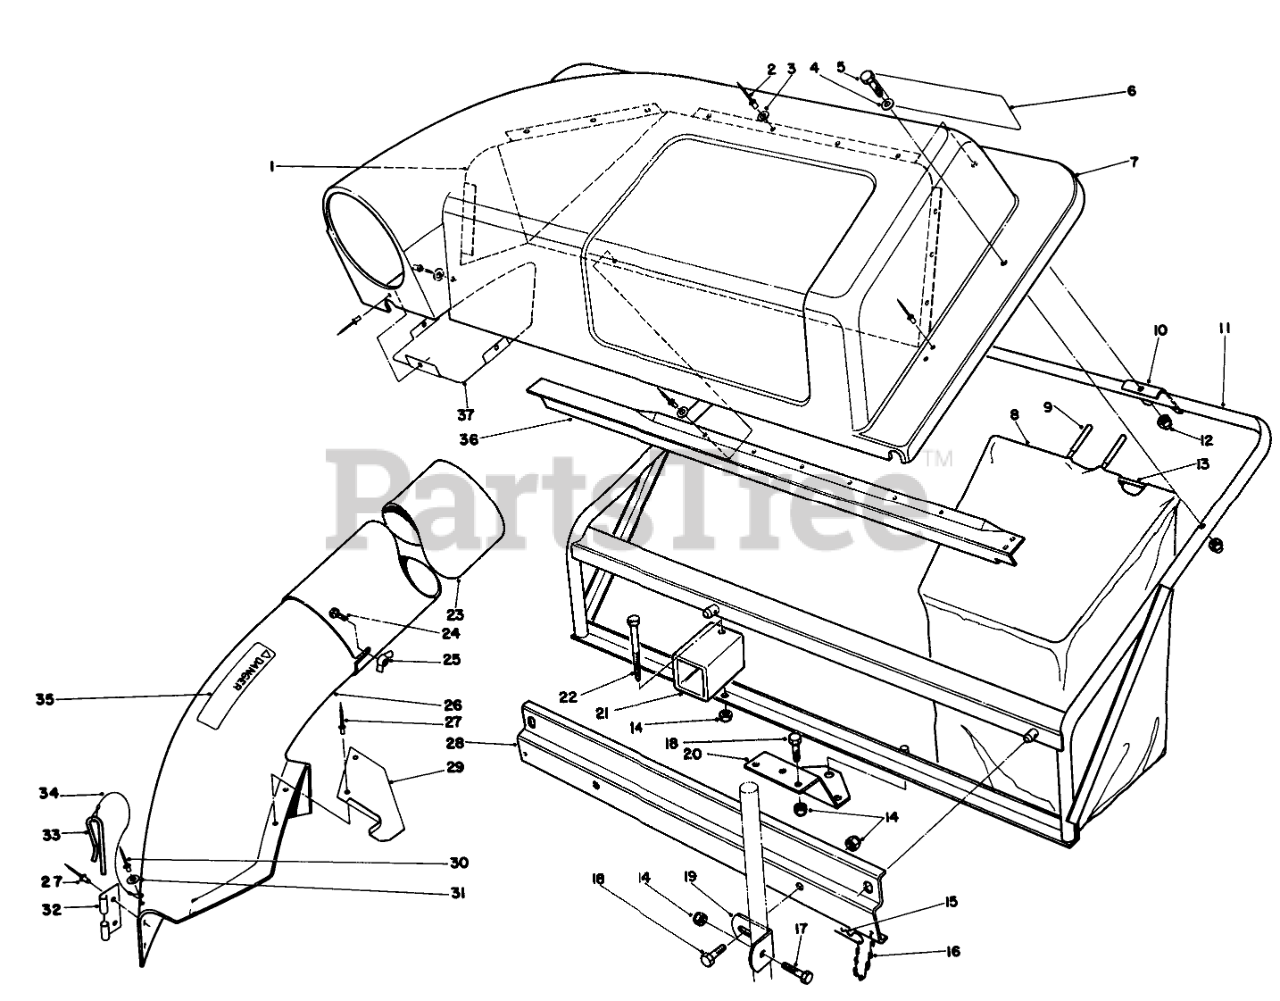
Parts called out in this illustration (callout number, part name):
1	Screen-Cover
2	Rivet-Pop
3	WASHER-FLAT
4	WASHER-PLAIN
5	SCREW-HH
6	TWIN BAGGER DECAL
7	Cover
9	GRIP-HANDLE, BAG
10	BAG FRAME BRKT
11	Frame
12	NUT-LOCK, CAP
13	Frame-Bag
14	NUT-LOCK, CONE
15	PIN-HAIR
16	6-LINK CHAIN W/HOOK
17	SCREW-HH
18	SCREW-HH
19	Bracket Mtg. Grass Catcher
20	MTG PLATE B
21	FRAME SUPT TUBE B
22	SCREW-HH
23	TUBE(ROUND&LONG)
24	BOLT-CARR
25	NUT-WING SPECL
26	Chute Assembly (Incl. Ref. #25, 27-33)
27	Rivet
28	Bracket-Frame Support
29	CHUTE SUPT BRKT
30	RIVET-BLIND
31	Washer
32	BRACKET-MOUNTING, CHUTE
33	PIN-LOCKING, CHUTE
34	LANYARD
35	Decal-Chute
36	SCREEN SUPT BRKT B
37	Shield Cover
